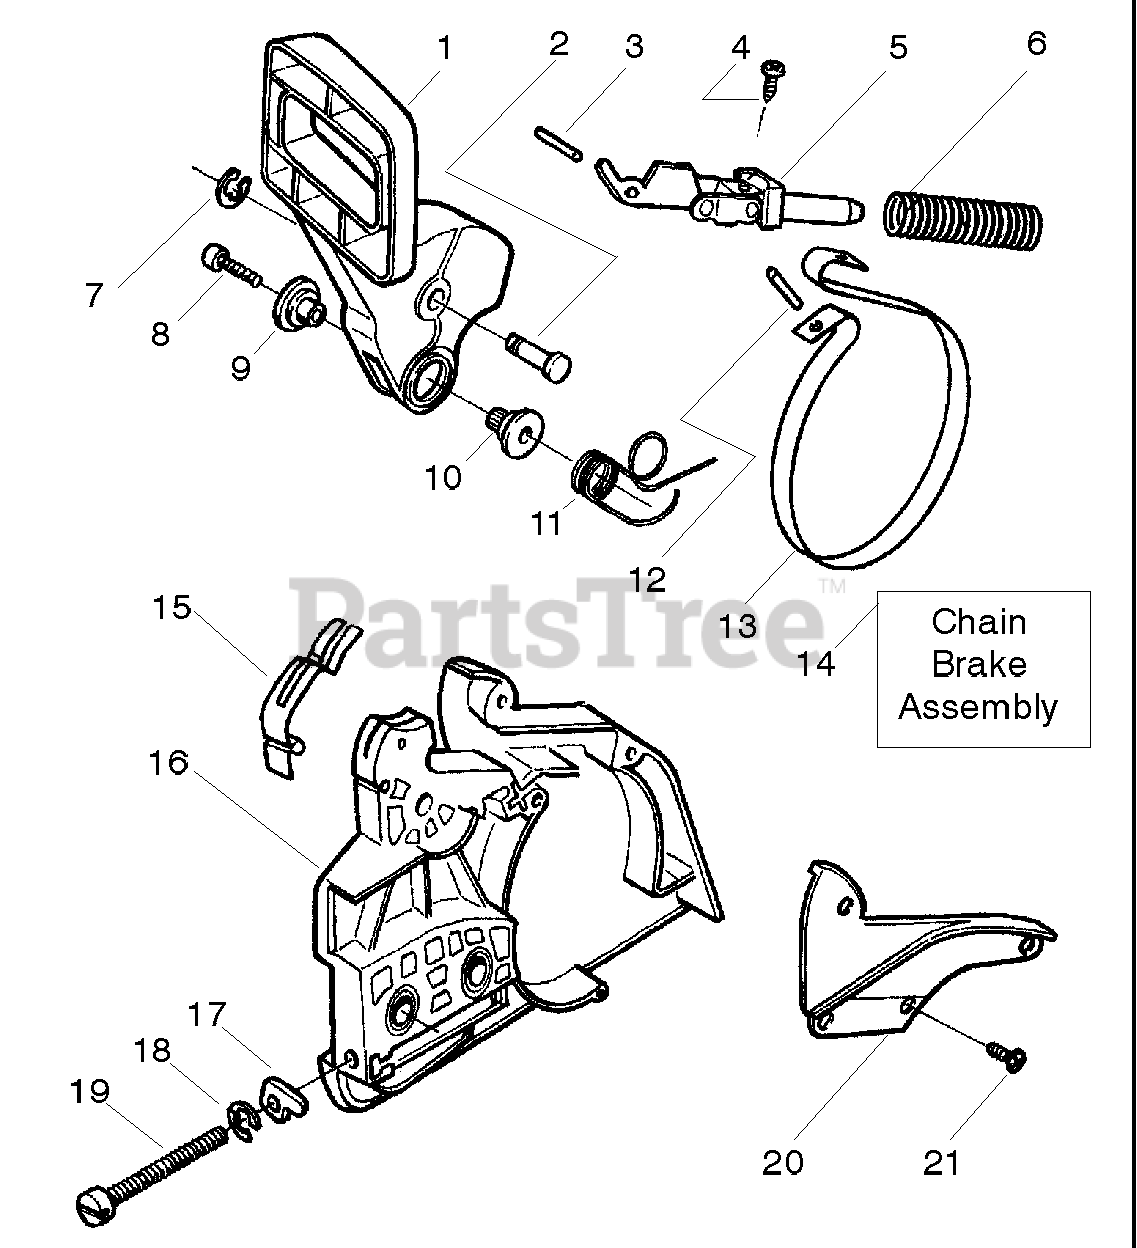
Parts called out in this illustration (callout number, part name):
1	Kit- Lever & Link Assy.
3	Pin- Link
4	Screw
5	Assy-Front Link
6	Spring-Chain Brake
9	Journal-Right
10	Journal-Left
11	Spring-Handguard
12	Pin-Spring
13	Band-Brake w/slots
14	Assy-Chain Brake
15	Spring-Position
16	Cover-Clutch
17	Pin-Bar Adjusting
19	Screw-Bar Adjusting
20	Cover-Chain Brake Spring
21	Screw
